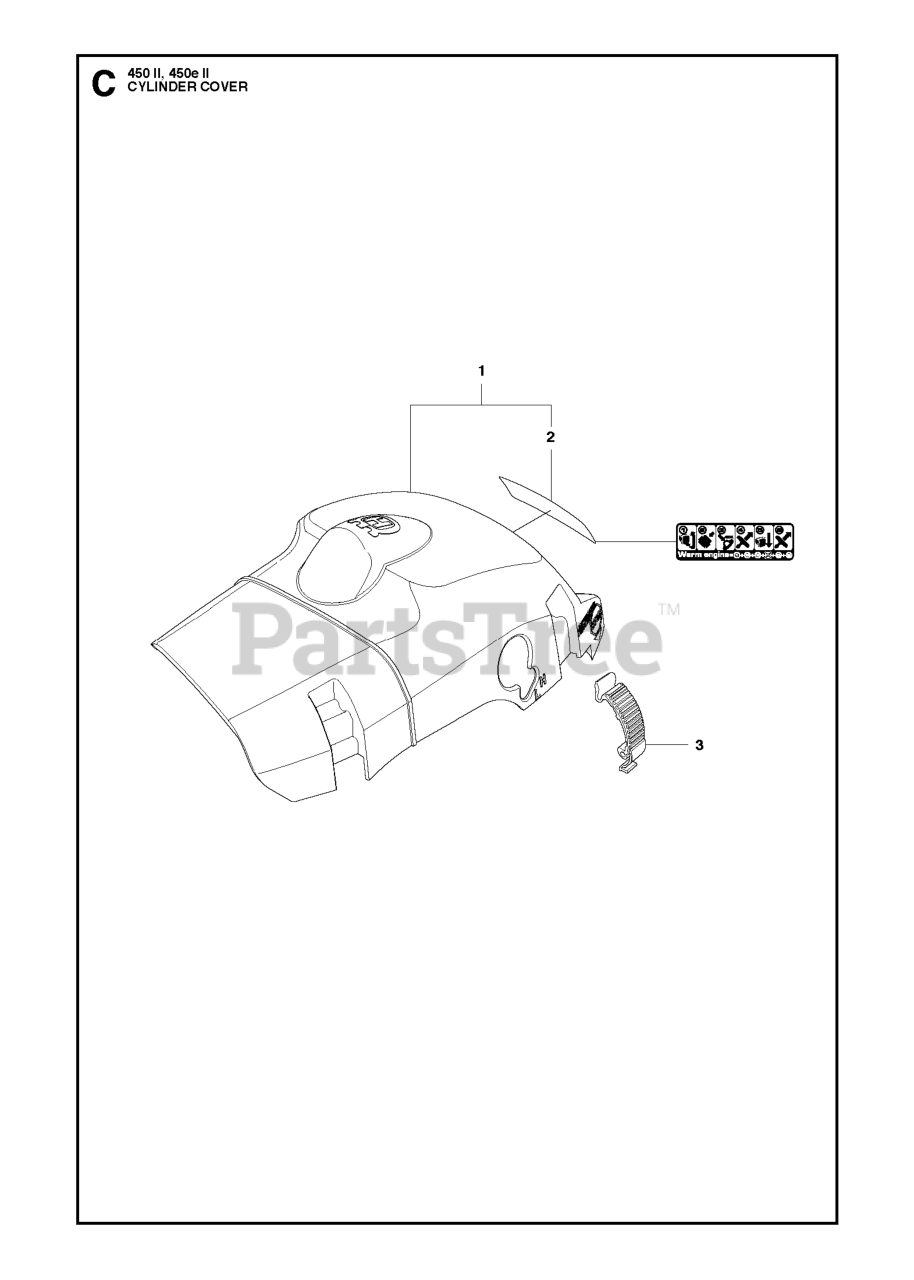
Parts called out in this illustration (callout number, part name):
1	CYLINDER COVER SYSTEM
2	LABEL START REMINDER
3	BUCKLE ORANGE
